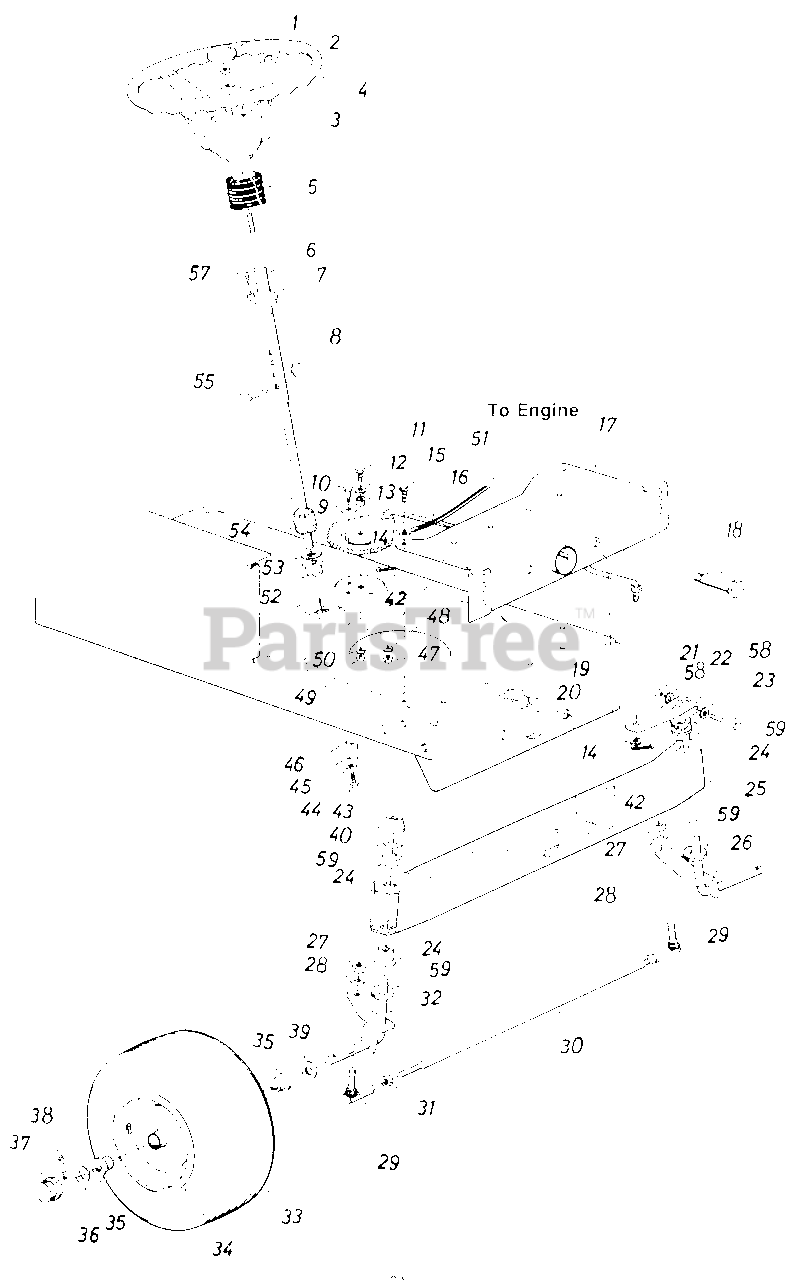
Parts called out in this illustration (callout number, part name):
1	Steering Wheel Cap
2	Hex Nut 5/16-18 Thd.*
3	Belleville Wash. .345" I.D.
4	Steering Wheel 12" Dia.
4	Steering Wheel 13.5" Dia.
5	Steering Bellow
6	Steering Column Ass'y.
7	Flange Bearing .890 I.D. x 1.36 O.D.
8	Internal Cotter Pin 1/4" Dia.
9	Fl-Wash. .438" I.D. x 1.37" O.D.
10	Shoulder Bolt .437" Dia. x .35 Lg. 5/16-18 Thd.
11	Hex Bolt 3/8-24 x 1.0" Lg. (Grade 5)
12	Fl-Wash. .38" I.D. x 1.0" O.D.
13	Spacer.380" I.D. x .625" O.D. x .227
14	Flat Washer .56 I.D. x 1.0 O.D.
15	Hex Wash. Hd. Self-Tap Scr.
16	Steering Drag Link
17	Front Pivot Brkt.
18	Shoulder Bolt .498" Dia. x 2.04 Lg. 3/8-16 Thd.
19	Hex Nut 3/8-16 Thd.*
20	L-Wash. 3/8" I.D.*
21	Hex Cent. L-Nut 5/16-24 Thd.
22	Steering Arm Front Axle
23	Hex Bolt 5/16-24 x 2.00" Lg. (Grade 5)
24	Hex Flg. Brg. .634 I.D.
25	Pivot Bar Ass'y.
26	Front Axle Ass'y. L. H .
27	Hex Nut 3/8-24 Thd.*
28	L-Wash. 3/8" I.D.*
29	Bal I Joi nt 3/8-24 Thd.
30	Tie Rod
31	Hex Jam Nut 3/8-24 Thd.*
32	Front Axle Ass'y. R.H..
33	Wheel Ass'y. Comp.
33	Tire Only
34	Front Wheel Rim Only
34	Air Valve
34	Grease Fitting
35	Bearing
36	Fl-Wash. .635 I.D. x 1.59" O.D.
37	Front Wheel Hub Cap
37	Front Wheel Hub Cap (Chrome)
38	Cotter Pin 118" Dia. x 1.25" Lg.*
39	Fl-Wash. .635" I.D. x 1.20" O.D.
40	Push Cap 5/8" Dia. Rod
42	Cotter Pin 118" Dia. x 1.0" Lg.
43	Hex L-Bolt 5/16-18 x .62" Lg.
44	L-Wash. 5/16" I.D.*
45	Fl-Wash. .344" I.D. x 1.25" O.D.
46	Spacer (Plastic)
47	Hex Nut 3/8-24 Thd.*
48	L-Wash. 3/8" I.D.*
49	Hex Nut 5/16-18 Thd.*
50	L-Wash. 5/16" I.D.*
51	Steering Gear Segment
52	Hex Flg. Brg. .634 I.D.
53	Fl-Wash. (Hardened)
54	Steering Shaft Lower
55	Clevis Pin 1/4" Dia. x 1.00" Lg.
57	Oval Hd. Cr. Sunk Scr. #10 x 5/8" Lg.
58	Bell-Wash.
59	Fl-Wash. (Hardened)
